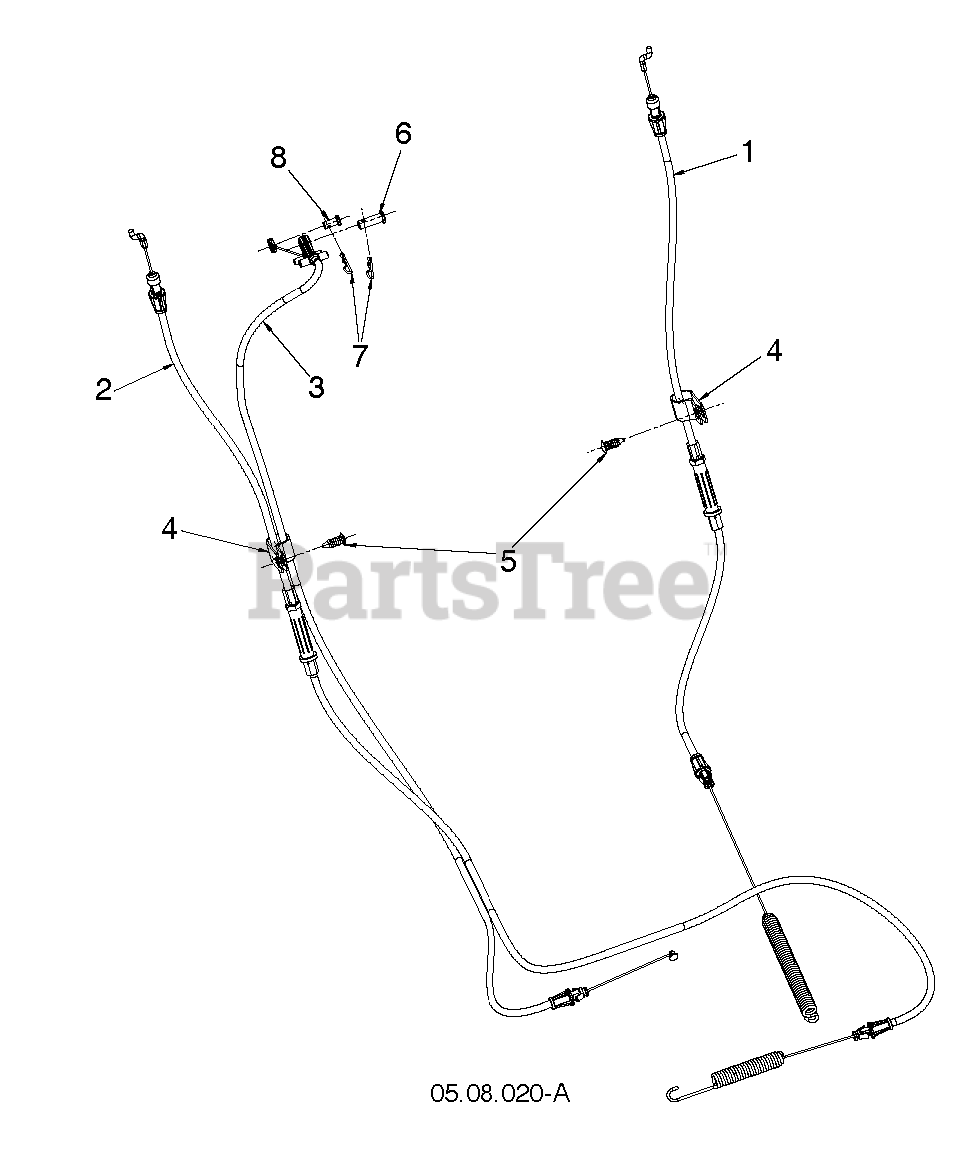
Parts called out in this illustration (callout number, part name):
1	CABLE.DRIVE CONTROL W/ADJ
2	CABLE.CONTROL.AUGER
4	CLIP.CABLE.BLK
5	FASTENER.PUSH.O.250X0.783
6	PIN CLEVIS 5/16X.875
7	HAIRPIN.SOFT.ZINC.059X1.125
8	PIN CLEVIS .25 X .31
